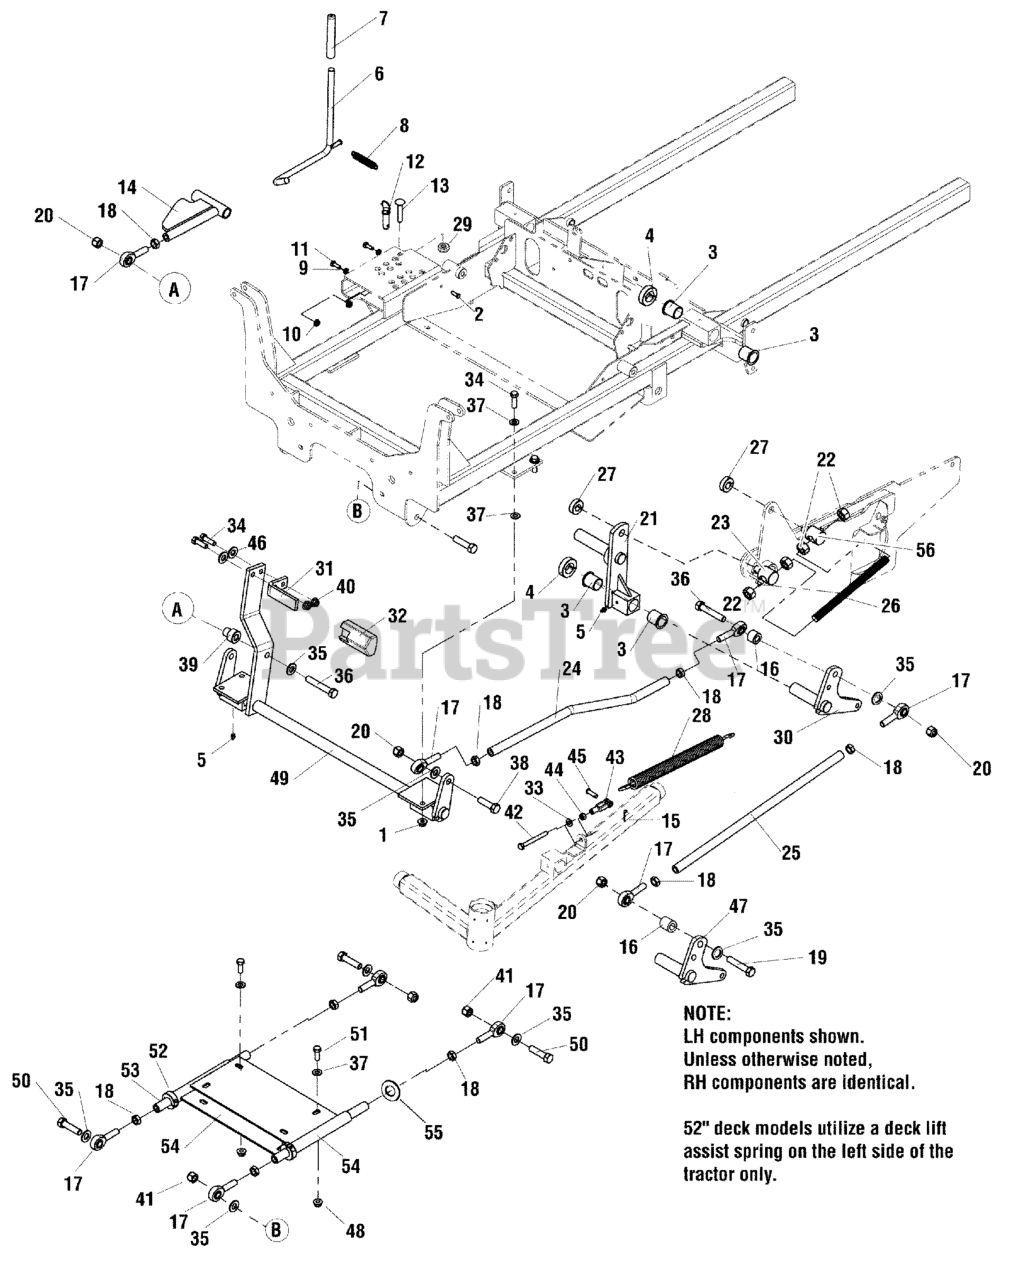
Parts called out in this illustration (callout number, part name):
1	NUT, 3/8 - 16 HEX NYLOCK FLANGE
2	PIN, CLEVIS, 1/4 X 7/8, PLATED
3	BUSHING, 1.00 X 1.13 X 1.38, Plastic
4	COLLAR, 1" Split
5	GREASE FITTING, 1/4-28 Straight
6	WELD, ROD DECK LIFT - BLK
7	GRIP, FOAM, .475 X 4.35 X .095
8	SPRING-EXT, .500 OD X 3.50 LG X .058 WR
9	WASHER, 1/4 SAE
10	NUT, 1/4-20 HEX SERR. FLANGE
11	BOLT, 1/4"-20 X 3/4" GD5 YZ
12	PIN, HITCH, 1/2 X 2.00 OAL, YP
13	BOLT, 3/8-16 X 2, CARRIAGE, GD5, CZ
14	WELD, DECK ADJUST LINK - RED MODEL
15	PIN, 3/32 X 0.750, COT, ZINC/CLEAR
16	SPACER, .52 X 1.00 X .75, CZ
17	BALL JOINT, 1/2-20, MALE
18	NUT, 1/2-20 Hex Jam
19	BOLT, 1/2-13 X 2-3/4 GD5 CZ
20	NUT, 1/2-13 HEX NYLON LOCK
22	NUT, Hex, 5/8-11
23	SPRING ROD PIVOT (52" Models Only)
24	ROD, DECK LIFT BENT
25	ROD, DECK LIFT OUTER, YZ
26	ROD, 5/8-11 X 9.00
27	COLLAR, 5/8" Split
28	SPRING-EXT, 1.00 ODX13.25LGX.177WR, BLK
29	NUT, Hex, Side Lock, 3/8-16
31	PEDAL, FOOT - BLK
32	PEDAL, Rubber
33	WASHER, 5/16 GRADE 9, FLAT
34	BOLT, 3/8-16 X 1-1/4" GD5 CZ
35	WASHER, 1/2" GD9 YZ
36	BOLT, 1/2-13 X 3-1/2, HEX HD, GD5, CZ (SV)
37	WASHER, 3/8 SAE
38	BOLT, 1/2-13 X 1-3/4 GD5 CZ
39	ADAPTER, CASTER AXLE, CZ
40	NUT, 3/8-16 HEX NYLON LOCK
41	NUT, Hex, Nylon Lock, 1/2-20
42	BOLT, 5/16-18 X 2-1/4 TFL, GD5 YZ
43	CLEVIS, 5/16-18, 5/16" PIN HOLE, STEEL
44	NUT, 5/16-18 HEX
45	PIN, CLEVIS, 5/16 X 1, PLATED
46	WASHER, 3/8" GR. 9 FLAT
48	NUT, 3/8-16 Hex Large Serrated Flange
49	WELD, DECK LIFT SHAFT - RED MODEL
50	BOLT, 1/2-20 X 1-3/4" GD8 CZ
51	BOLT, 3/8-16 X 1" GD5 CZ
52	COLLAR, 3/4" Split
53	SHAFT, DECK STABILIZER
54	WELD, DECK STABILIZER - BLK
55	WASHER, 1/2 SAE
